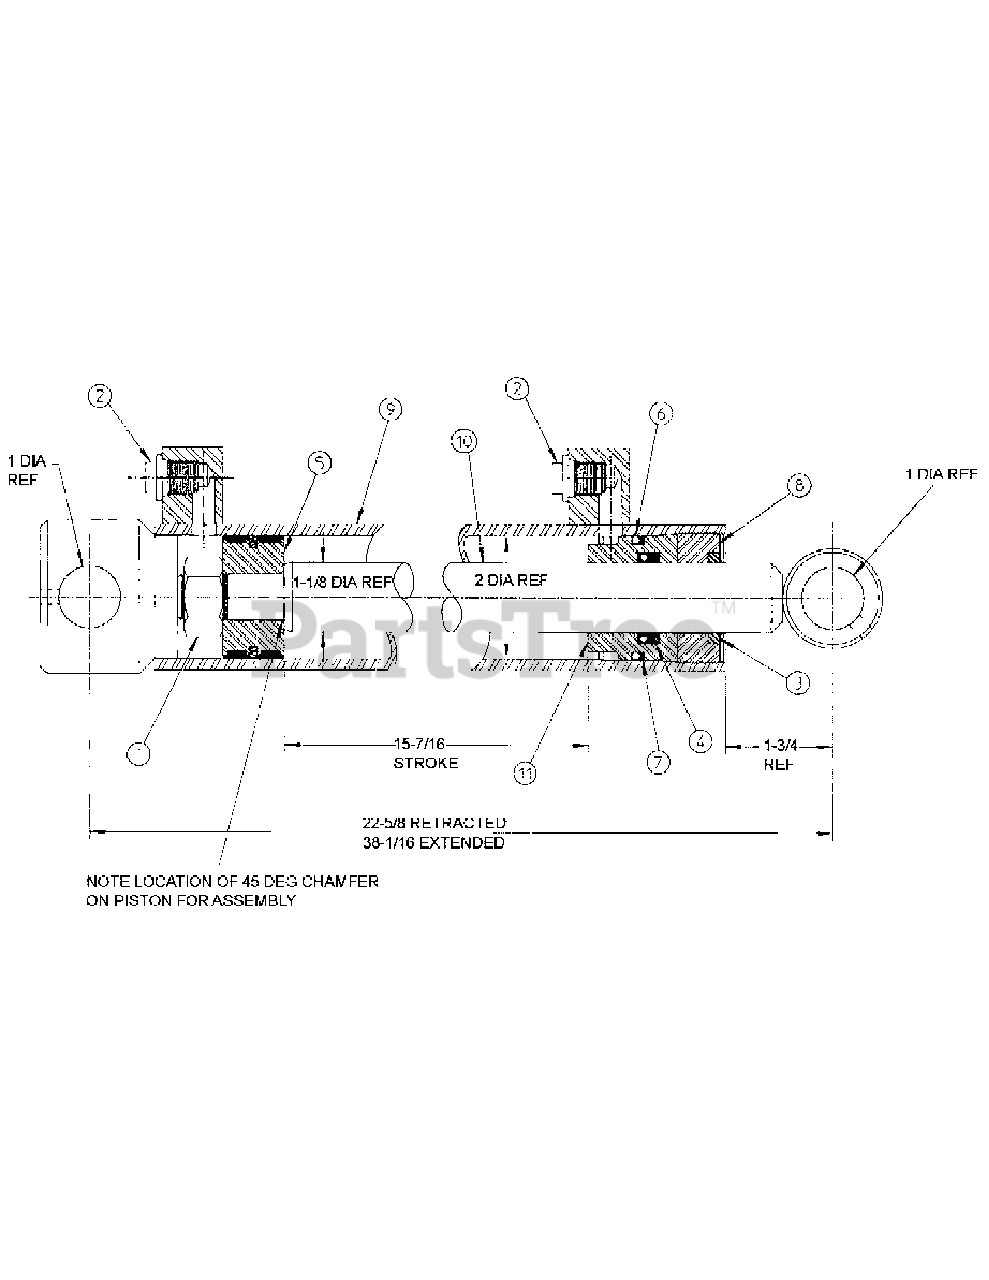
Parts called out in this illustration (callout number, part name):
1	NUT, 3/4'' NF LOCK
3	ROD WIPER
4	ROD SEAL
6	O-RING, 2''OD X 1-3/4'' ID
7	BACK-UP RING
8	GLAND NUT (LESS ROD WIPER)
9	CYLINDER TUBE WELDMENT
10	PISTON ROD WELDMENT
11	GLAND WITH O-RINGS, BACK-UP, ETC
